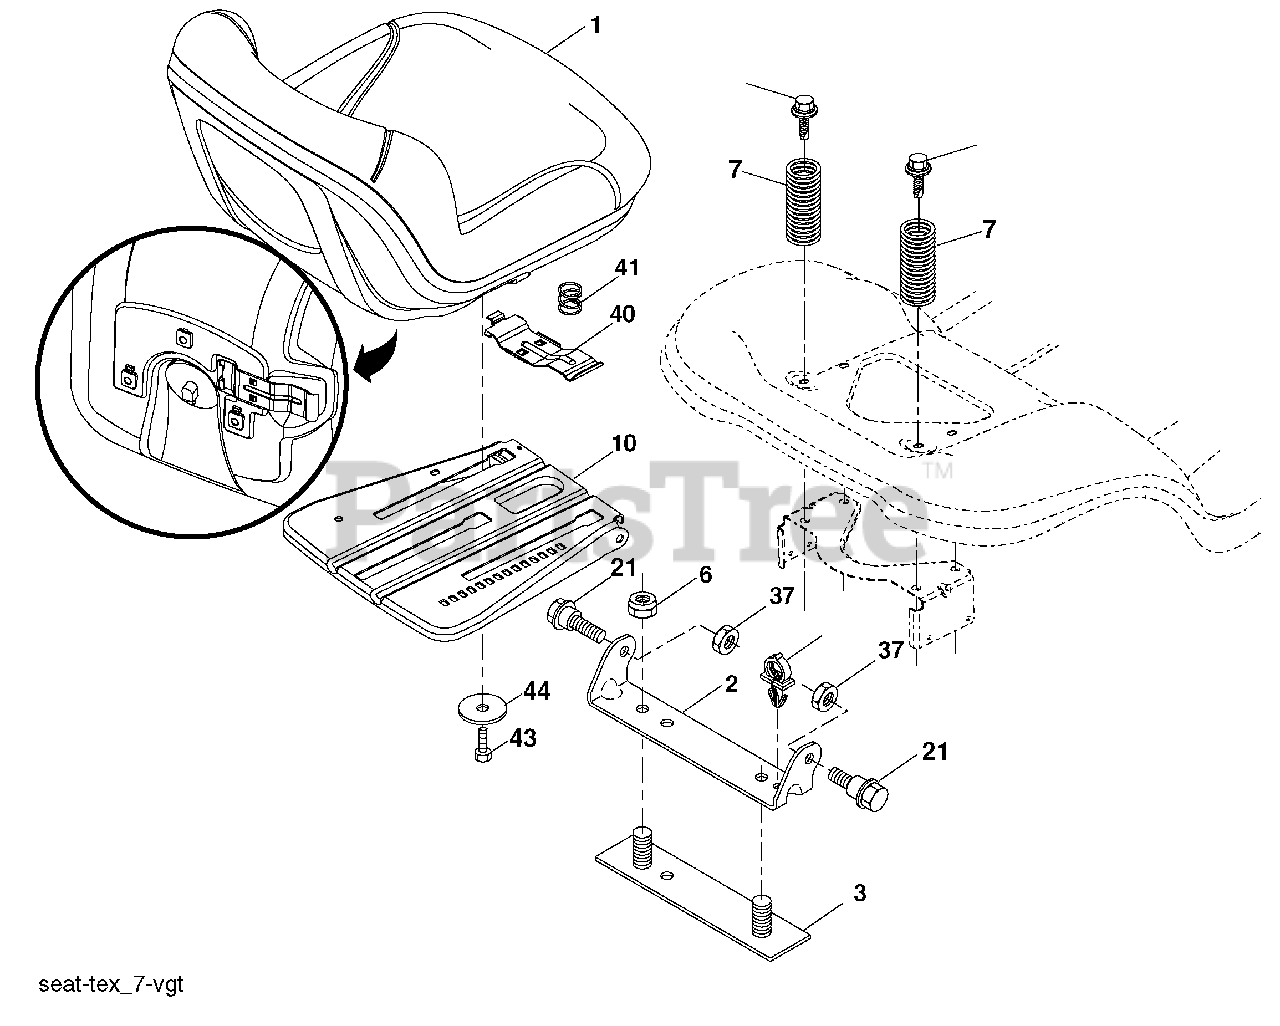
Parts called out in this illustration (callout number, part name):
1	Seat
2	Bracket Pivot Fender
3	Strap, Asm Fender
5	Clip, Push In, Hinged
6	Nut, Lock W/Ins. 3/8-16 unc
7	Spring, Seat Cprsn
8	Bolt 5/16-18 unc x 3/4 w/Sems
10	Pan, Seat
21	Bolt, Shoulder 5/16-18
37	Nut, Lock 5/16-18 unc
40	Handle Slide Seat
41	Spring Latch Seat
43	Bolt Fin Hex 3/8-16 unc x 3/4
44	Washer 13/32 x 2-3/8 x 12Ga.
